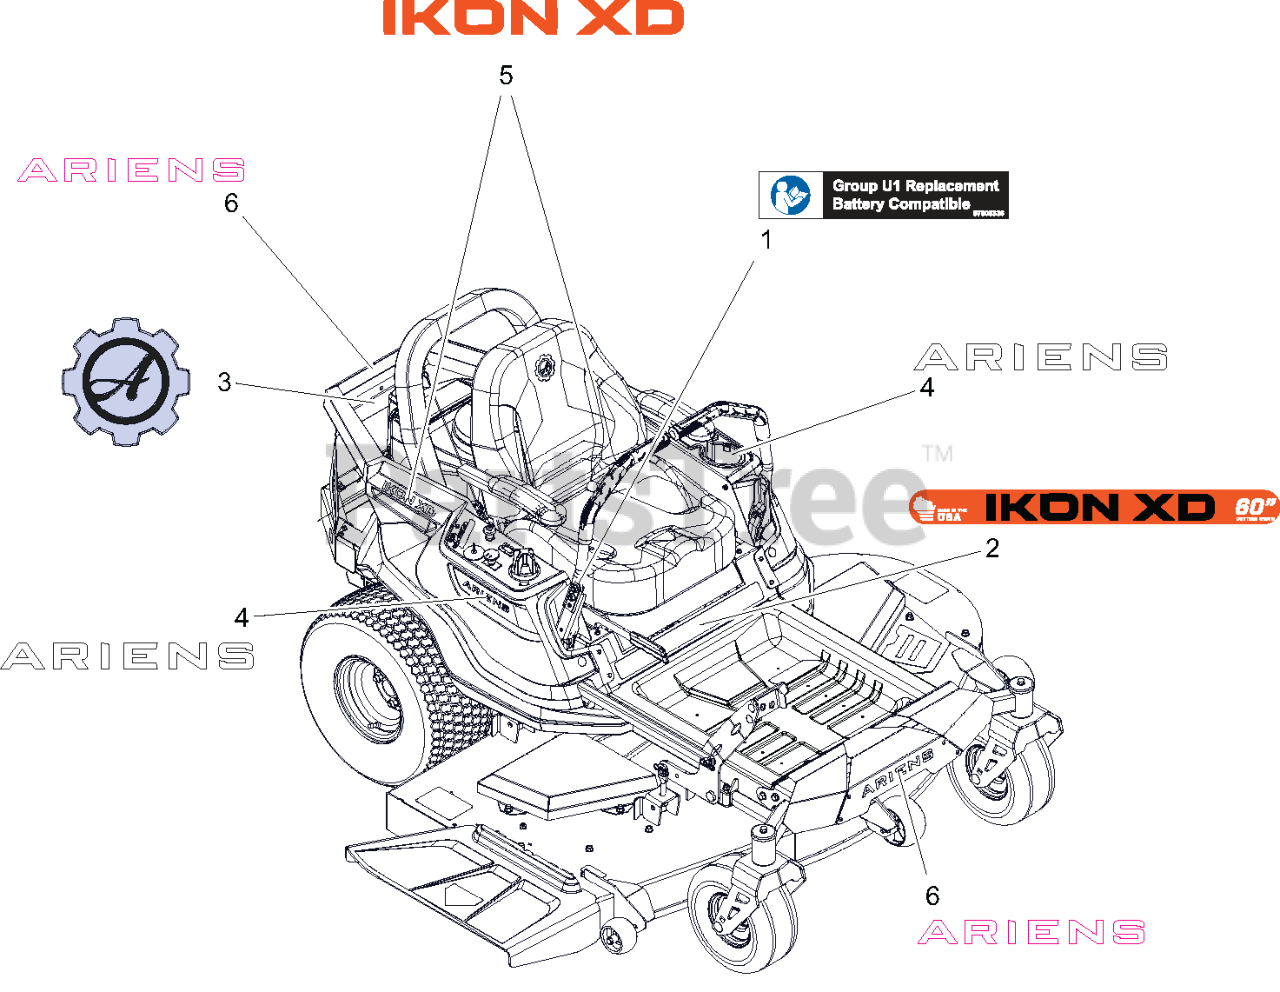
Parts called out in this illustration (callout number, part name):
1	DECAL, U1 BATTERY REPLACEMENT
2	DECAL, IKON XD - 60
3	DECAL, ARIENS - GEAR BADGE
4	DECAL, ARIENS (6.50")
5	DECAL, FENDER - IKON XD
6	DECAL - ARIENS 9.625"
